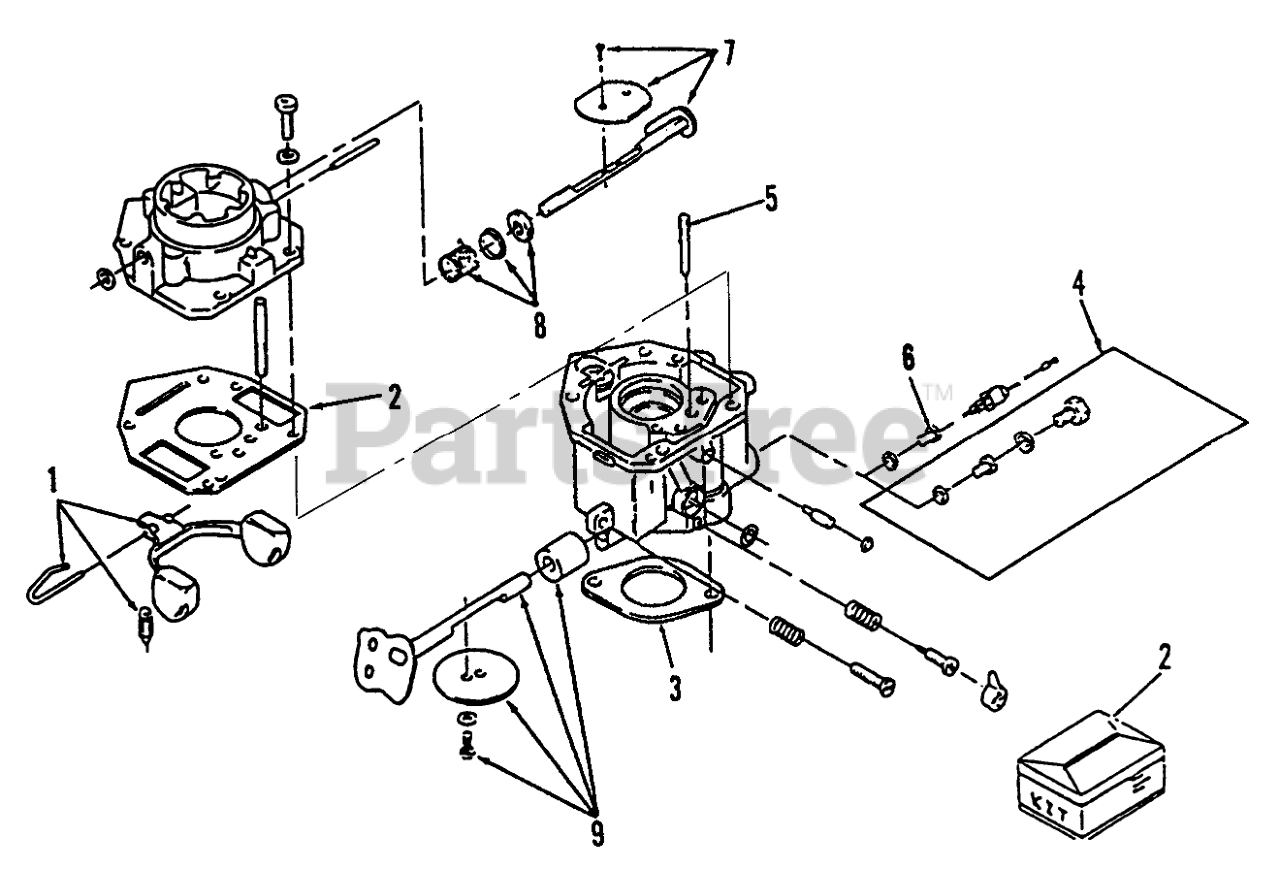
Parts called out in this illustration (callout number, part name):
1	Kit-Float (Incl.Float,Pin,&Valve)
2	Kit-Repair (Incl.Screw&Plug Package,Gasket Package,Float Valve,Idle Adjustment Needle&Spring,Mounting Gaskets,&Idle Limit Cap)
3	GASKET-CARBURETOR
4	FIXED-JET PKG
5	Idle Jet
6	POWER JET
7	Kit-Choke Shaft (Incl. Choke Valve, Valve Screw-Set, & Air Filter)
8	Kit-Choke Lever (Incl. Choke Lever Ring, Choke Spring,&Choke Collar)
9	Kit-Throttle Shaft (Incl. Valve Screw-Set, Air Filter,& Throttle Valve)
